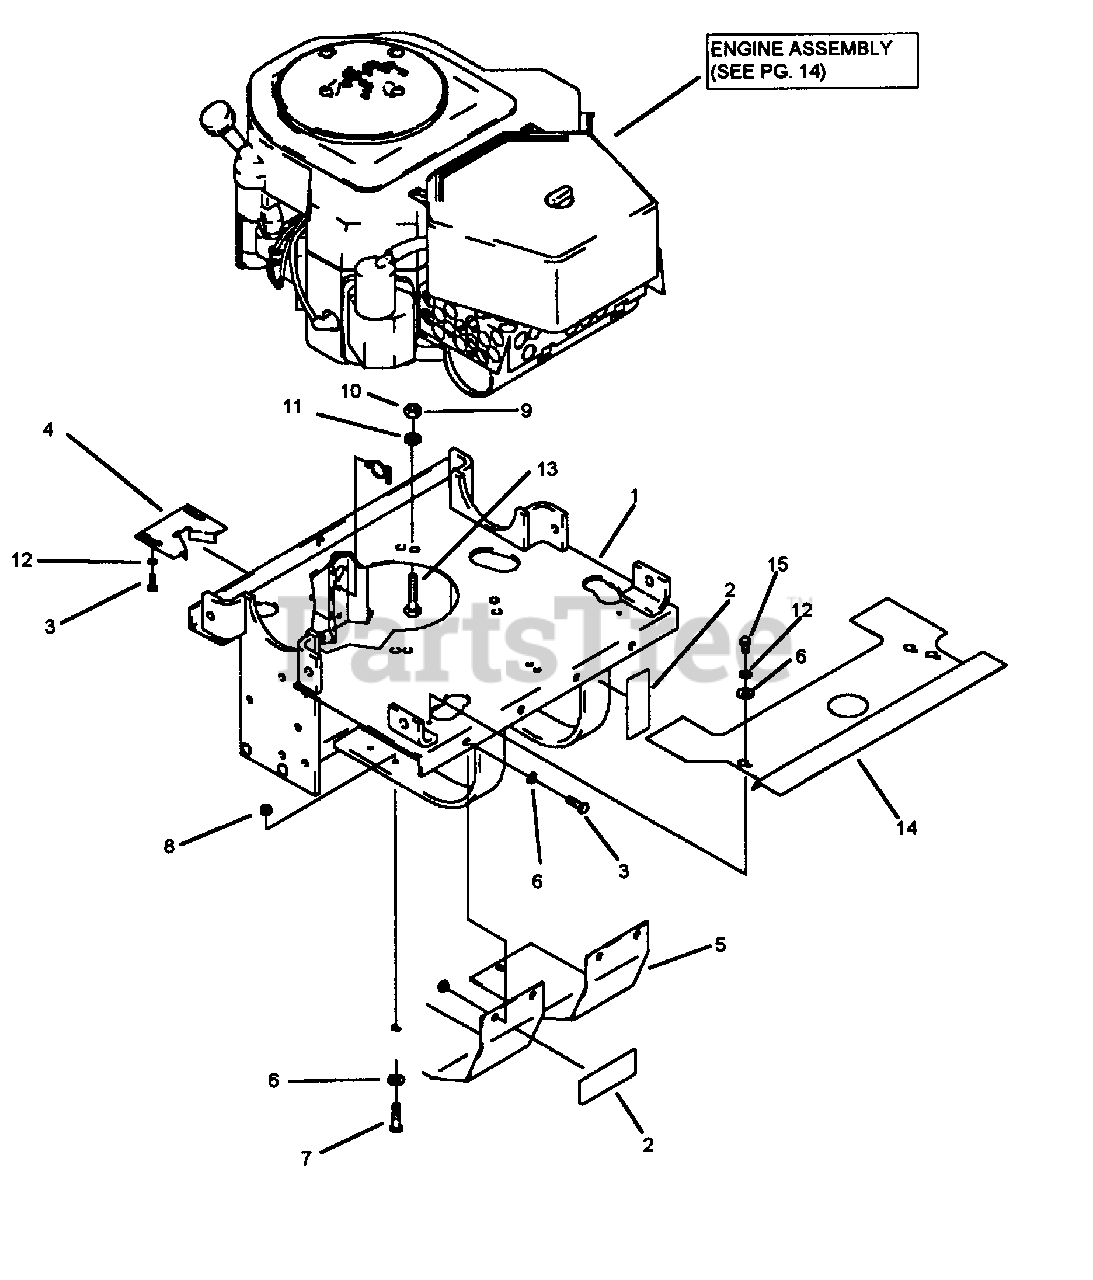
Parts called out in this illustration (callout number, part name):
3	CAPSCREW, 1/4-20 X 3/4" GR.5
4	CLUTCH STOP PLATE
5	FAN SHIELD
6	WASHER, FLAT, STD. 1/4
7	CAPSCREW, 1/4-20 X 1 GR.5
8	NUT, HEX, HD. 1/4-20, NYLOC
9	NUT, 5/16-18 UNC, GR5 PLATED
10	LOCKWASHER, 5/16, SPLIT SPRING
11	BLINDHOLE KURLY, LOC
12	LOCKWASHER, SPLIT SPRING 1/4",
13	BOLT, 5/16-18 X 1-1/2 GR5
15	SCREW, 1/4" X 3/8" SELF THRD FORM
